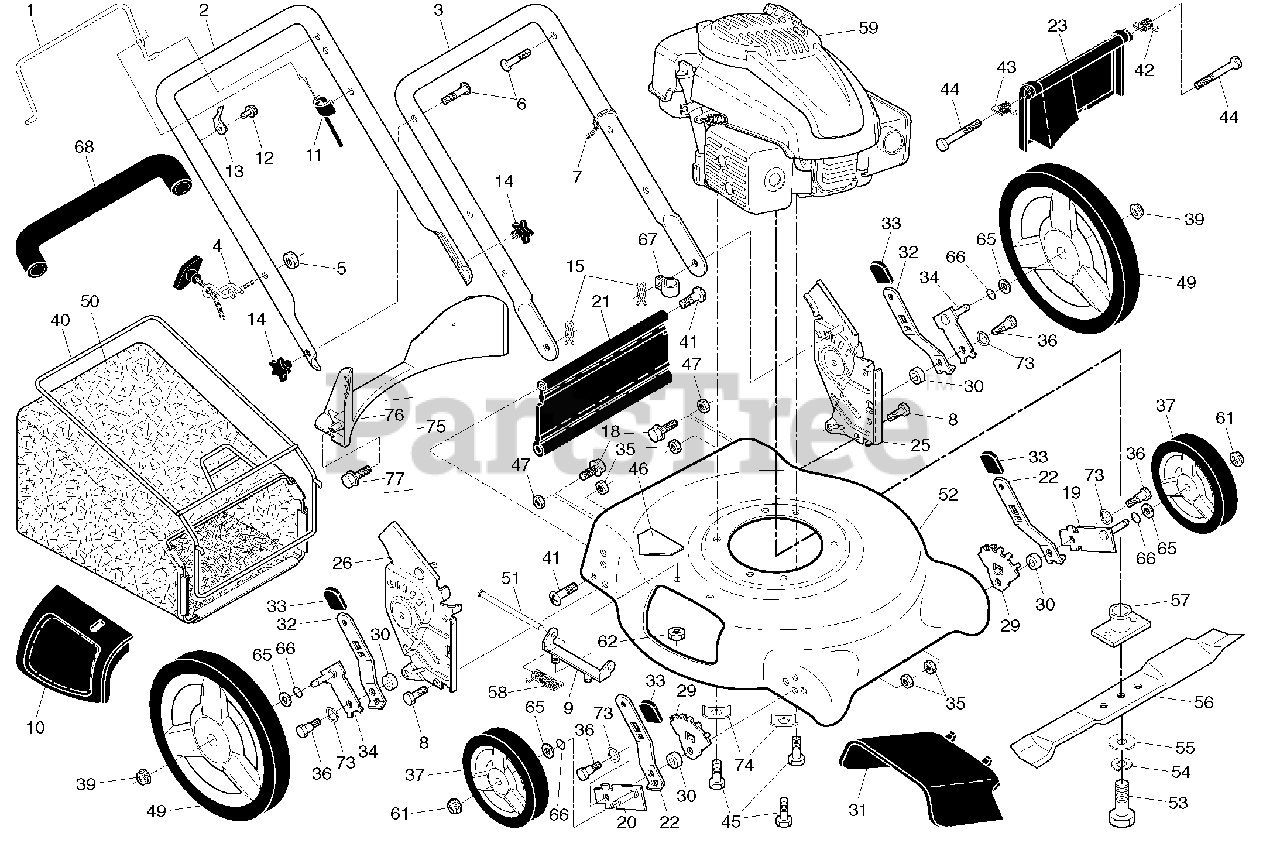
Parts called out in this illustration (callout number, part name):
1	Control Bar
2	Upper Handle
3	Lower Handle
4	Rope Guide
5	Nut, Hex
6	Handle Bolt
7	Wire Tie
8	Bolt, Hex Head 5/16-18 x 3/4
9	Hinge Bracket
10	Mulcher Door
11	Engine Zone Control Cable
12	Hex Washer Head Screw
13	Up-Stop Bracket
14	Handle Knob
15	Hairpin Cotter
18	Screw 1/4-20 x 3/8
19	Axle Arm Assembly, Front, LH
20	Axle Arm Assembly, Front, RH
21	Kit, Rear Skirt
22	Selector Spring, Front
23	Rear Door Assembly
25	Handle Bracket Assembly, LH
26	Handle Bracket Assembly, RH
29	Wheel Adjusting Bracket
30	Spacer
31	Discharge Deflector
32	Selector Spring, Rear
33	Selector Knob
34	Axle Arm Assembly, Rear, LH
35	Locknut, Hex 5/16-18
36	Shoulder Bolt 5/16-18
37	Wheel & Tire Assembly, Front
39	Flanged Locknut, Hex
40	Frame, Grassbag
41	Hinge Screw
42	Spring, Rear Door, LH
43	Spring, Rear Door, RH
44	Bolt, Rear Door
45	Screw, Hex Head, Threaded, Rolled 3/8-16 x 1
46	Danger Decal
47	Nut, Hex
48	Axle Arm Assembly, Rear, RH
49	Wheel & Tire Assembly, Rear
50	Grassbag
51	Hinge Rod
52	Kit, Housing
53	Screw, Hex Head, Grade 8 3/8-24 x 1-3/8
54	Helical Lockwasher
55	Hardened Washer
56	21" Blade
57	Blade Adapter
58	Hinge Spring
59	Engine, Kohler, Model Number XT149-0026-EA (See Breakdown)
61	Nut, Hex
62	Locknut, Hex 1/4-20
65	Washer, Flat
66	O-Ring
67	Clip, Cable
68	Grip, Foam
71	Gas Can (2.5 Gallon Container)
71	Fuel Stabilizer
71	SAE 30W Oil (20 Ounce Bottle)
73	Washer, Curved
74	Washer, Special, Engine
75	Kit, Rear Baffle
76	Baffle, Rear
77	Screw, Rear Baffle
